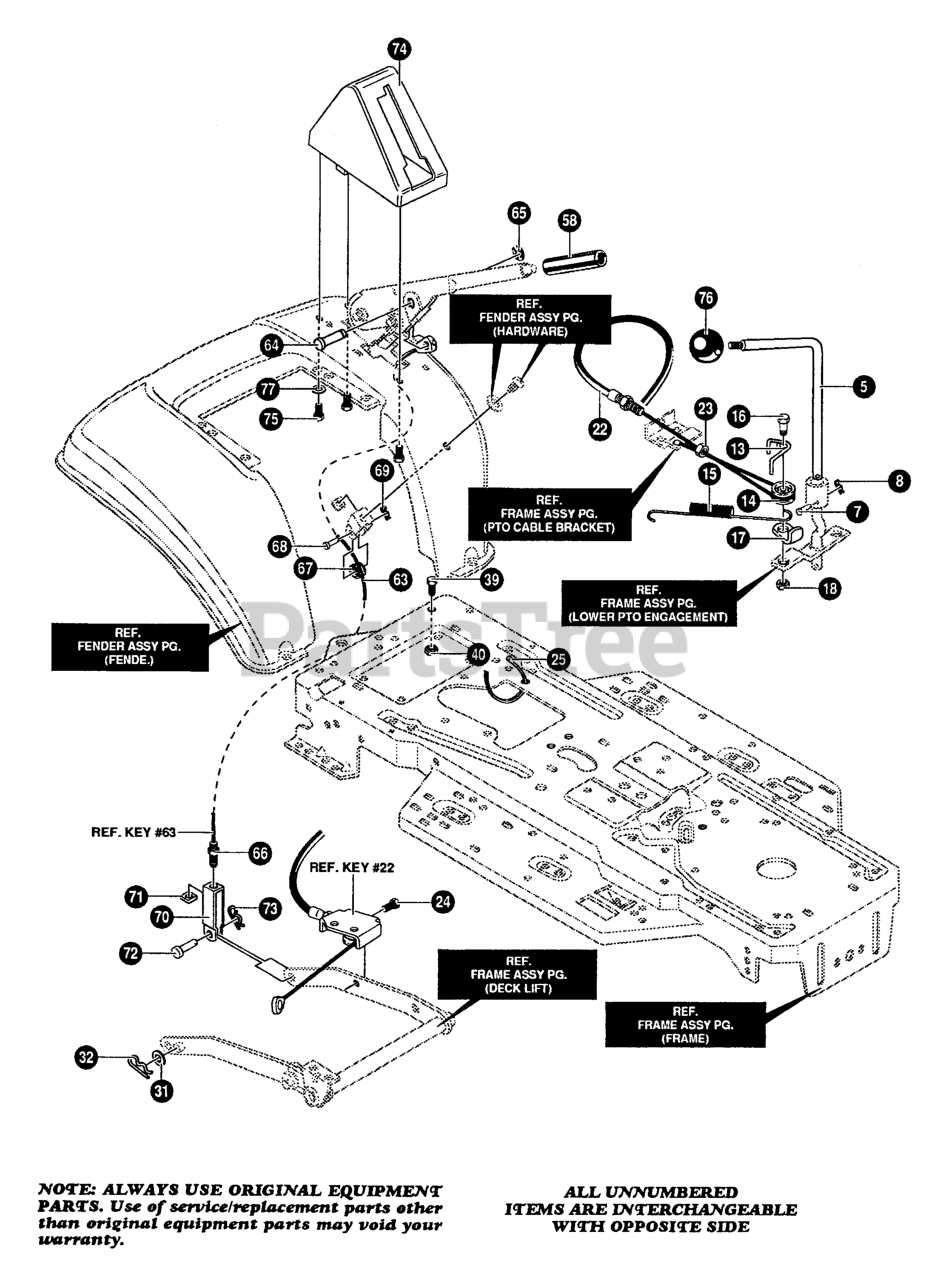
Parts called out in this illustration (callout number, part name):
5	LEVER, PTO UPPER
7	PIN, CLEVIS
8	PIN, HAIR
13	SPRING, CABLE KEEPER
14	PULLEY, METAL
16	BOLT, .375 x .565
17	BRACKET, CABLE RETAINER
18	NUT, 1/4-20
22	ASSEMBLY, CABLE PTO ENGAGE
23	NUT, 1/4-28
24	SCREW, 5/16-18 x 0.75
25	TIE, CABLE
31	WASHER, FLAT .531 x 1.06 x .063
32	PIN, HAIR
39	SCREW, 5/16-18 x 0.75
40	NUT, 5/16-18
58	GRIP, W/HOLE BLACK
63	ASSEMBLY, CABLE LIFT
64	PIN, CLEVIS
65	RING, RET E
66	NUT, 1/4-20
67	PULLEY, METAL
68	PIN, CLEVIS
69	PIN, HAIR
70	CLEVIS, LIFT CABLE
71	NUT, 1/4-20
72	PIN, CLEVIS
73	PIN, COTTER
74	LIFT COVER
75	SCREW, #10 x .75
76	KNOB, ROUND
77	WASHER, FLAT .281 x .63 x .065
